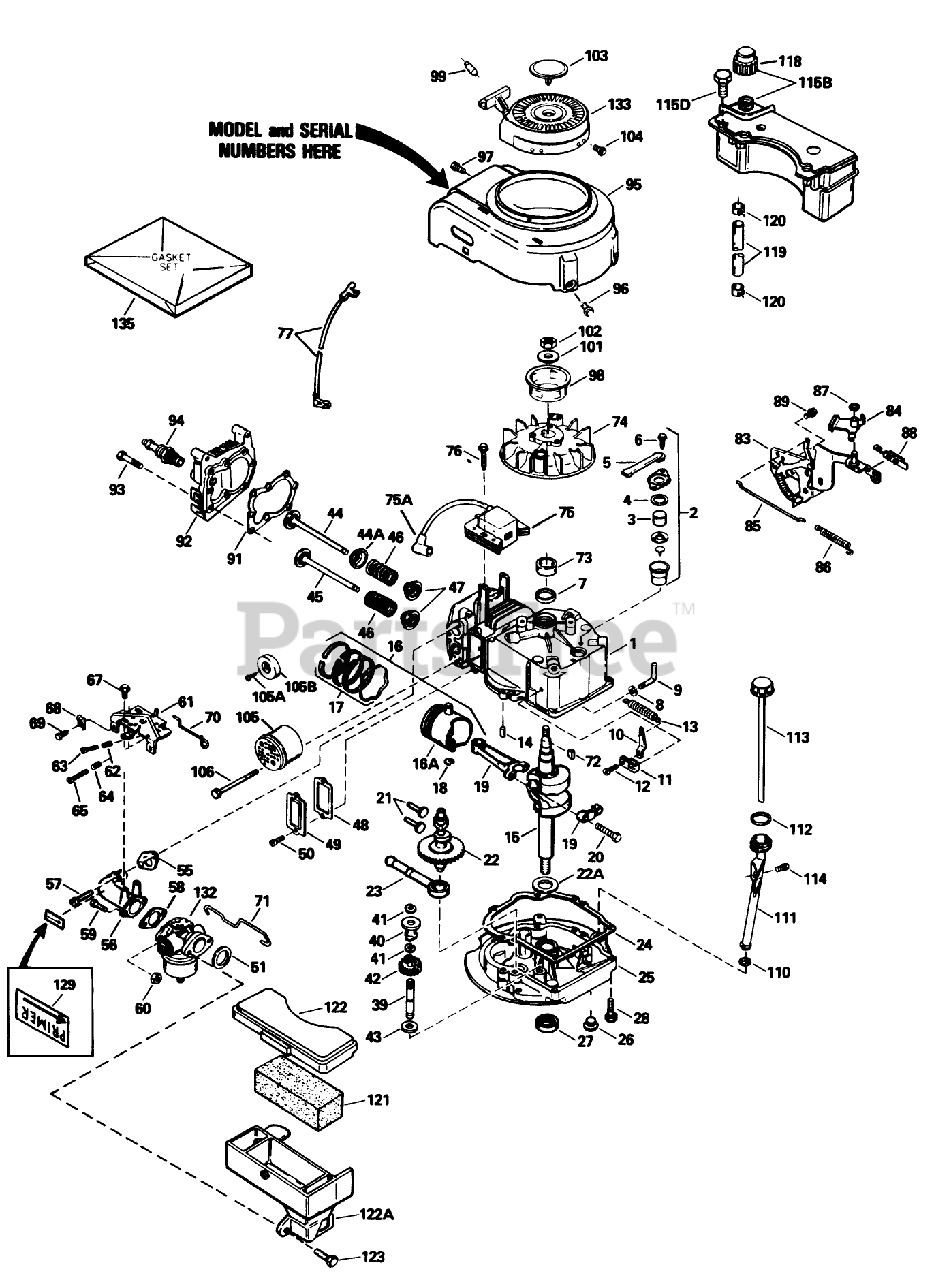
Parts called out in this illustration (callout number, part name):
1	Cylinder Assy. (Incl. #24)
2	Breather Assy. (Incl. Ref. #46 thru 51)
3	Element-Breather
4	Gasket-Breather
5	Tube, Breaker
6	Screw (10-24 x 9/16)
7	Seal-Oil
8	Washer-Flat
9	Rod, Governor (Incl. No. 36)
10	Governor Lever
11	Clamp-Lever, Governor
12	Screw
13	Spring Governor
14	Pin-Dowel
15	Crankshaft
16	Piston-Pin Ring Assy. (Std.)(Incl. Ref. #16A, 17 18)
16	Piston-Pin Ring Assembly (.010 oversize)(Incl. Ref. #16A, 17 18)
16	Piston, Pin Ring Assy. (.020 Oversize)(Incl. Ref. #13A, 14, 15)
16A	Piston Pin Assy. (Std.)(Incl. Ref. #14)
16A	Piston Pin Assembly (.010 oversize)(Incl. Ref. #18)
16A	Piston Pin Assy. (.020 Oversize) (Incl. Ref. #14)
17	Ring Set-Piston (Std.)
17	Ring Set, Piston(.0100versize)
17	Ring Set (.020" OS)
18	Ring-Retaining, Piston Pin
19	Rod Assy., Connecting (Incl. Ref. #17)
20	Bolt-Rod, Connecting
21	Lifter-Valve
22	Camshaft(Mech.Comp. Release)
22A	Washer-Thrust
23	Oil Pump ASM
24	Gasket
25	Flange-Mounting (Incl. Ref. #26, 27 39)
26	Plug Oil Drain
27	Seal-Oil
28	Screw (1/4-20 x 1-1/4)
39	Shaft-Governor
40	Spool-Governor
41	Ring-Retaining
42	Governor Gear ASM
43	Washer
44	Valve, Intake (Std.) (Incl. Ref. #40)
44	Valve, Intake (1/32" oversize)(Incl. No. 40)
44A	Seal Assy., Intake
45	Valve, Exhaust (Std.)(Incl. No. 40)
45	Valve, Intake (1/32" oversize)(Incl. No. 40)
46	Spring-Valve
47	Cap-Valve, Spring
48	Gasket-Cover, Valve
49	Cover-Valve
50	Screw
51	Gasket-Cleaner, Air
55	Gasket-Intake Pipe
56	Pipe-Intake (Incl. Ref. #59)
57	Screw (1/4-20 x 1)
58	Gasket
60	Nut and Lock Washer (1/4-28)
61	51089 SUPP TO MANUA
62	61709/GIL1515A/95-5
63	Screw
64	Spring-Compression
65	Screw
67	Screw (10-24 x 9/16)
68	Conduit
69	Screw (10-32 x 3/8)
70	2035A67 ADD.ASSEMBL
71	Link-Throttle
72	Key-Flywheel
73	Spacer
74	Flywheel
75	Solid State
75A	Cover-Spark Plug
76	Screw
77	Ground Wire
83	Bracket-S.E. Brake
84	Lever-Brake
85	Link-Control
86	Spring-Extension
87	Ring-Retaining
88	Terminal
89	Screw (1/4-20 x 3/8)
91	Gasket-Cylinder Head
92	Head-Cylinder
93	Screw (5/16-18x1-1/2)
94	Spark Plug-Resistor (R J19 L M)
95	Housing-Blower
96	Screw (1/4-20 x 1/2)
97	Screw (10-24 x 9/16)
98	Hub-Starter
99	Retainer-Starter Rope
101	Washer-Belleville
102	Nut-Flywheel
103	Plug Starter
104	Screw, Hex Hd.
105	Muffler Assembly (Incl. Ref. #106)
105A	Cover-Muffler
105B	Screw (8-32 x 3/8)
106	Screw
110	Gasket
111	Oil Fill Tube
112	O-Ring
113	Dipstick
114	Screw (10-32 x 1/2)
115B	Tank Assembly-Fuel (Incl. Ref. #102)
115D	Screw (10-32 x 35/64)
118	Cap-Fuel
119	Line-Fuel
120	Clamp-Line, Fuel
121	Filter-Air Cleaner
122	Cover Air Cleaner
122A	Body Air cleaner
123	Screw
129	Decal-Primer
132	Carburetor (Incl. Ref. #83)
133	Starter-Rewind
135	Gasket Set (Incl. Items Marked *)
